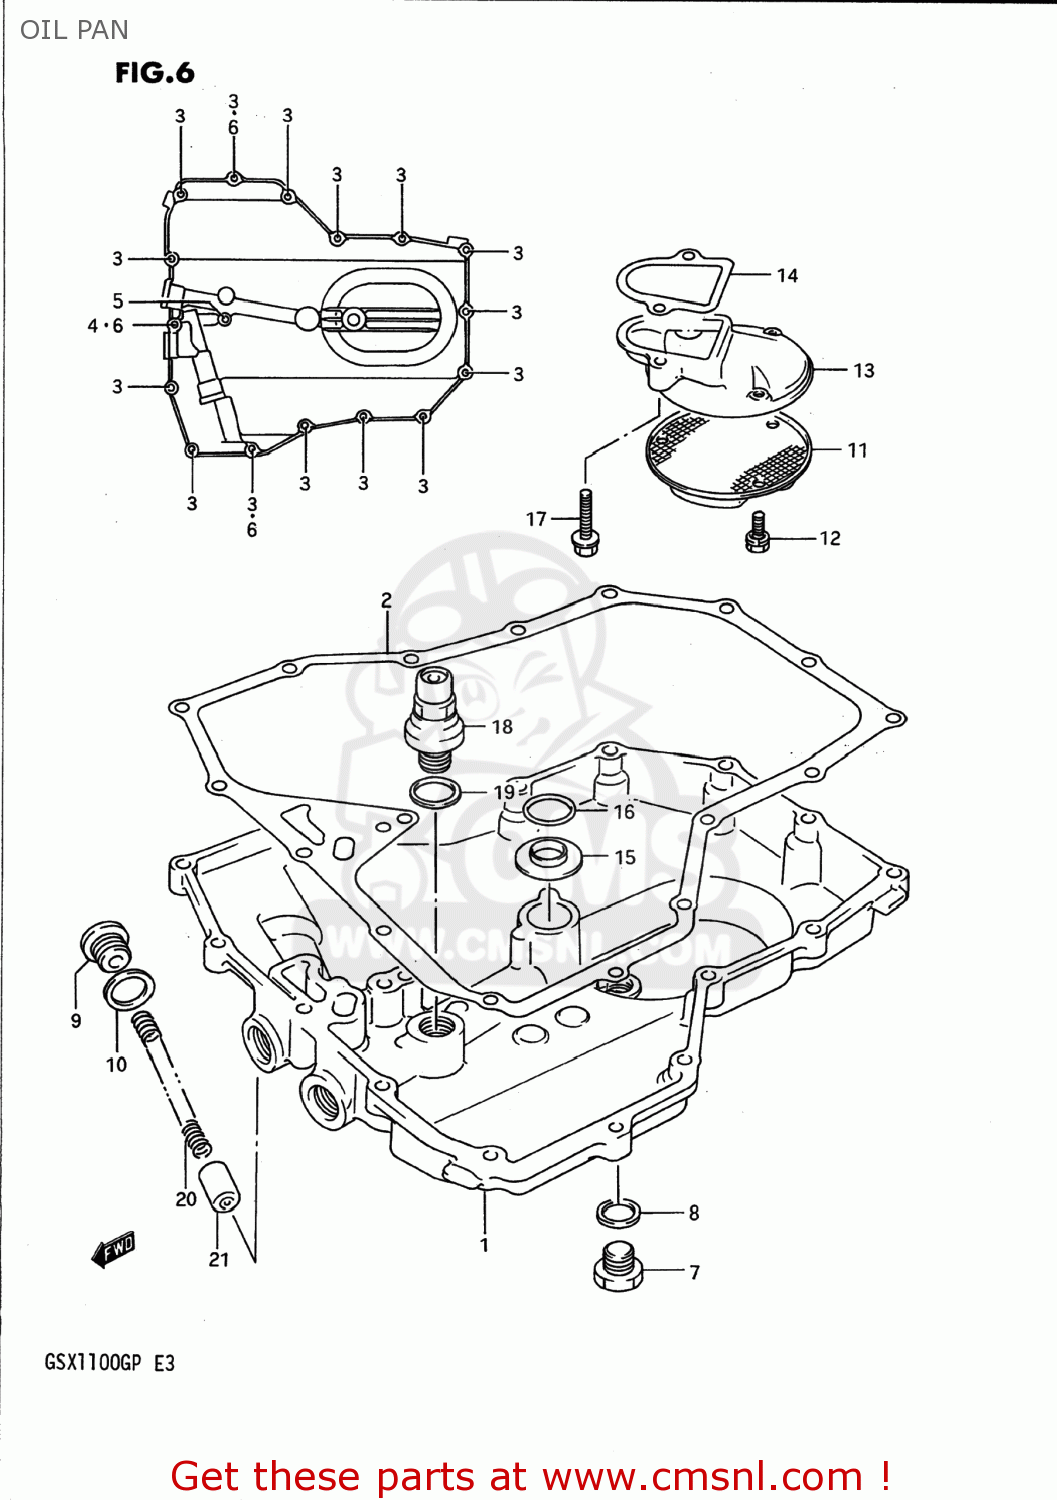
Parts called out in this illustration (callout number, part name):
1	PAN,OIL
2	GASKET,OIL PAN (NAS)
3	BOLT
4	BOLT
5	BOLT
6	GASKET(5.8X11X1.2) (NAS)
7	PLUG
8	GASKET(14X19.2X2) (NAS)
9	PLUG,16X8
10	GASKET(16X22X2) (NAS)
11	STRAINER,ENGINE OIL
12	BOLT
13	PROTECTOR,OIL STRAINER
14	O-RING
15	GASKET,OIL OUTLET (NAS)
16	O RING(D:3.2,ID:17.8)
17	BOLT 6X25
18	VALVE ASSEMBLY,OIL RELIEF
19	GASKET(16X22X2) (NAS)
20	SPRING
21	PLUNGER,OIL CONTROLL
